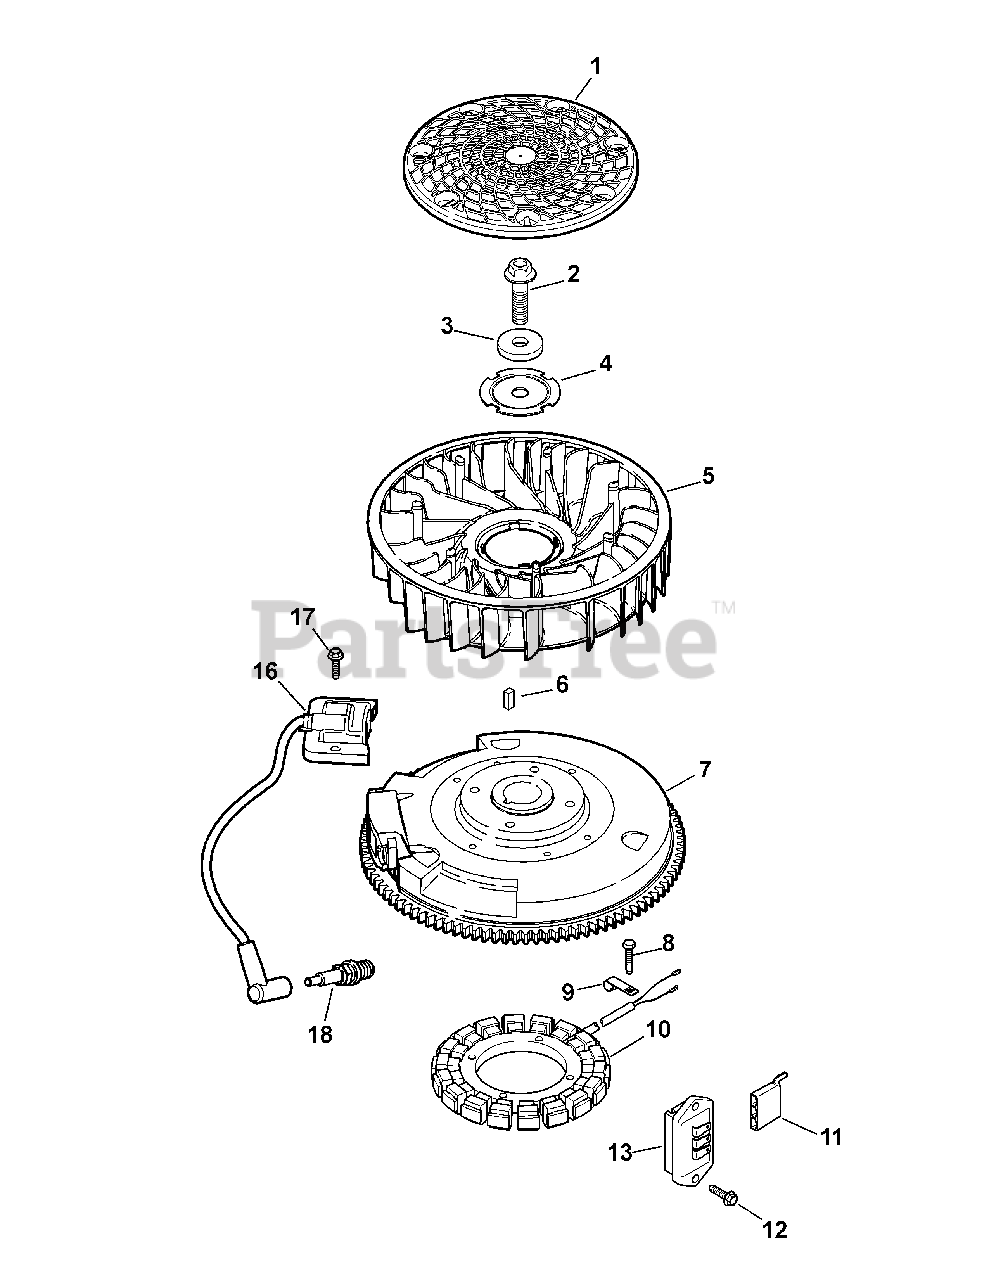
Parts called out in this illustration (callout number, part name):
2	Hex Flange Screw
4	Fan Mounting Plate
6	Straight Flywheel Key
7	Flywheel
8	Thd. Frm. Screw, M5 X 0.8 X 25
10	15 Amp Stator Kit
12	Flg. Thd. Frm. Screw, M5 X .8 X 20
13	Regulator/Rectifier
16	Ignition Module (CDI Fixed)
17	Flg. Thd. Frm., M5 X .8 X 20
18	Spark Plug (Std)
